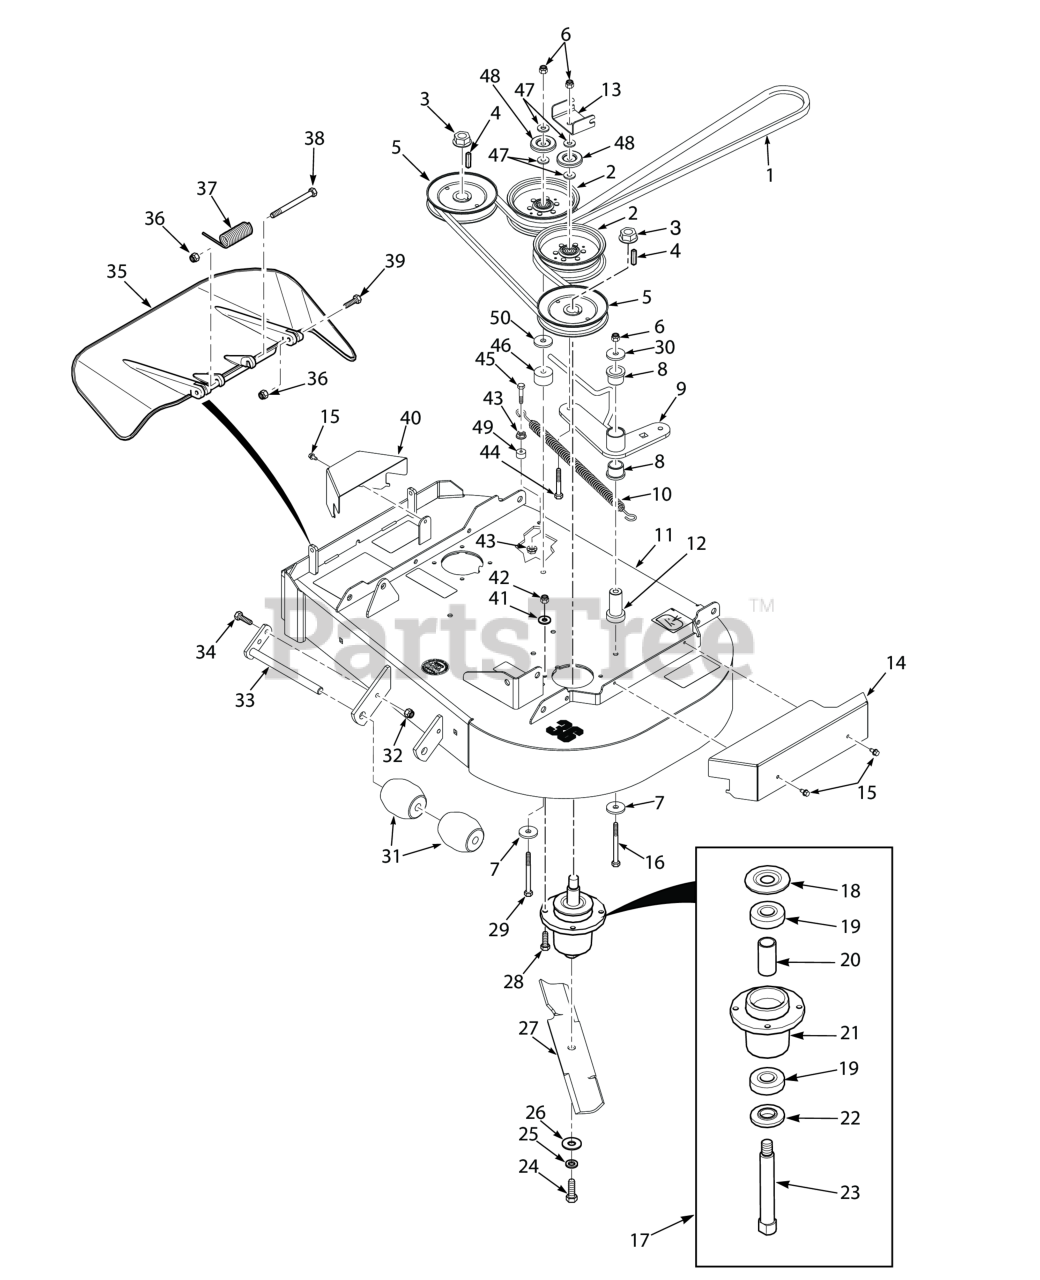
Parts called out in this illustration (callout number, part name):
1	Belt, Cutter Deck
2	Pulley, 5" Idler
3	Nut, 3/4-16 Spriral Lock
4	Key, 1/4 x 1/4 x 1.25" Pulley Mtg.
5	Pulley, 5.73" OD - 25mm Bore
6	HEX NUT, ELASTIC STOP LOCK, 3/8-16
7	Flatwasher, 3/8-.406 x 2.25" x .1875
8	Bearing, Plastic
9	Pivot, Idler
10	Spring, Cutter Deck Idler
11	Cutter Deck w/Decals, SWZT36H
12	Pivot, Idler
13	Bracket, Belt Guide
14	Belt Cover LH SMZL-36
15	Screw, 1/4-20 x .375"
16	Bolt, Hex Head 3/8-16 x 4.00
17	Spindle Assembly
18	Debris Shield
19	Bearing
20	Spacer, Bearing
21	Spindle Housing Assembly
22	Protector, Bearing
23	Shaft, Spindle
24	Bolt, Hex Head 5/8-11 x 1-1/2"
25	Lockwasher, 5/8" Spring
26	Flatwasher, 5/8-.688 x 1-3/4 x .134 HD
27	Cutter Blade, 18" (52V)
28	Bolt, Hex Head 5/16-18 x 1-1/2" Grade 8
29	Bolt, Hex Head, 3/8-16 x 3-1/2"
30	Flatwasher, 3/8-.406 x 1-1-1/2 x 7 Gauge
31	Wheel, Anti-Scalp
32	Nut, Flange Head Elastic Stop 5/16-18
33	Shaft Weldment, Guide Roller
34	Bolt, Heax Head 5/16-18 x 1" (48V / 52V)
35	Discharge Chute Assy. SFZ48
36	HEX NUT, ELASTIC STOP LOCK, 5/16-18
37	Spring, Discharge Chute
38	Bolt, 5/16-18 x 4-3/4" Hex Head
39	Bolt, Hex Head 5/16-18 x 1-1/2" - Front
40	Belt Cover, RH SMZL-36
41	Lockwasher, 5/16 (.317 x .586 x .078) Helical Spring
42	Lock Nut, 5/16-18 Elastic Stop Grade 8
43	NUT, 3/8-16 SERRATED FLANGE HEX HEAD
44	Capscrew, Hex Head 3/8-16 x 2-1/2"
45	Bolt, Hex Head 3/8-16 x 1-1/2" Grade 8 Black
46	Spacer, Idler Pulley
47	Flatwasher, 3/8 (.391 x .938 x .105 HD) Grade 8
48	Quick Pin, 5/16" Dia.
49	SPACER, IDLER
50	Flat washer, 1/4-.266 x .875 x .125
